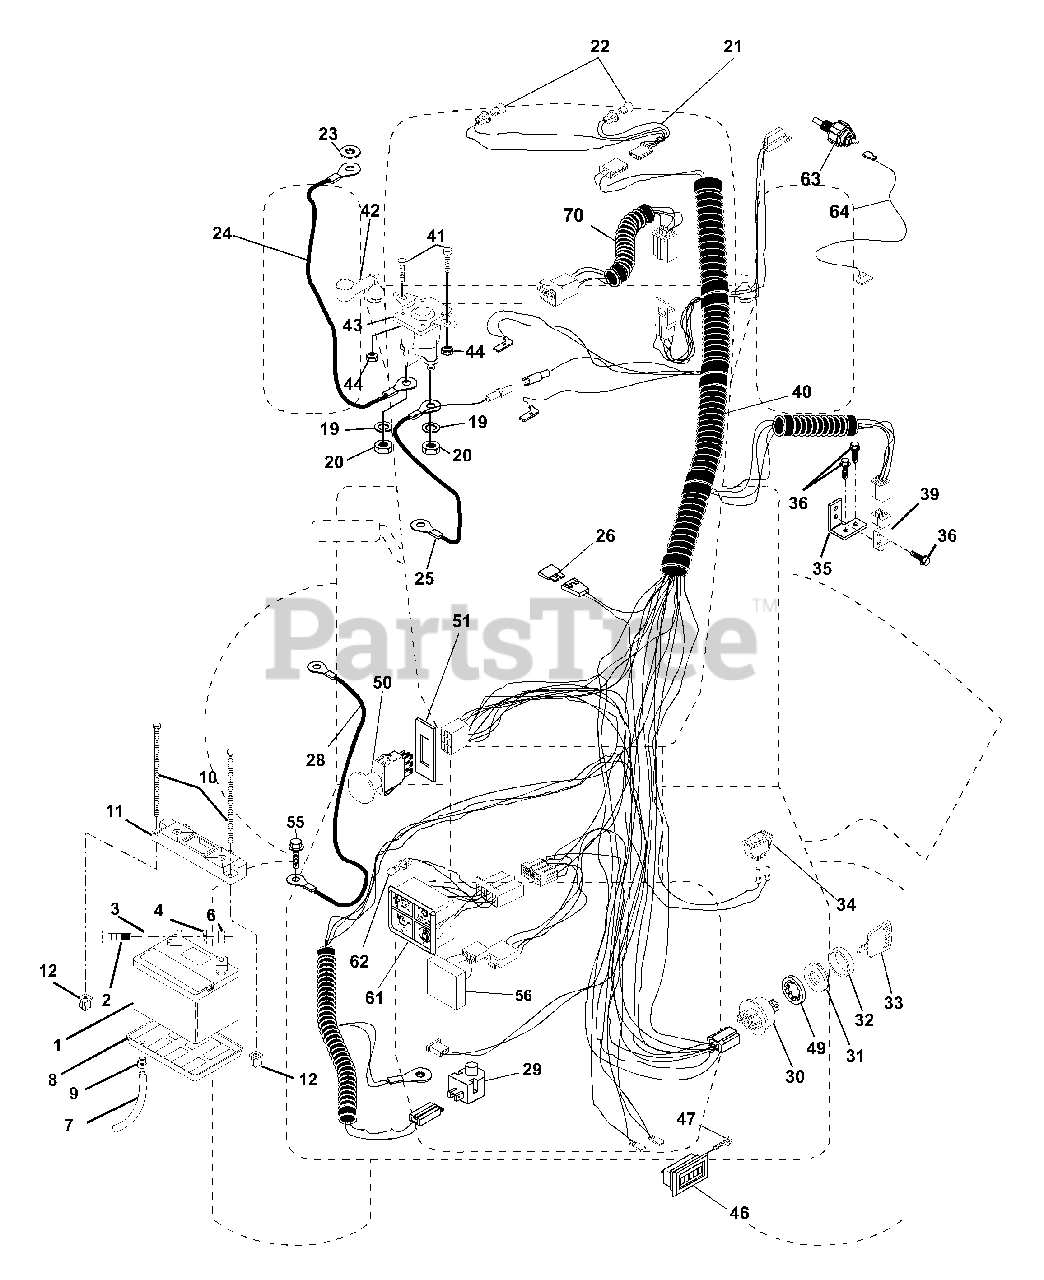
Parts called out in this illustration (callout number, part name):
1	Battery
2	Bolt, Hex Head 1/4-20 x 3/4
3	Washer 9/32 x 5/8 x 16 Gauge
4	Washer, Lock 1/4
5	Caps, Battery
6	Nut, Hex 1/4-20
7	Tube, Tray, Battery
8	Tray, Battery
9	Clamp, Hose
10	Bolt Battery Frt 1/4-20 x 3/4 Zinc
11	Holddown Battery Dash Mount
12	Push Nut Nylon 1/4" Battery Fnt.
19	Washer, Lock 1/4
20	Nut, Hex, Jam 1/4-20
21	Harness, Socket, Light
22	Bulb, Light
24	Cable Starter 6 Ga. 11" Red
25	Cable 6 Ga. Red 22' W/16 Wire
28	Cable, Ground 21" Black 6 Ga.
29	Switch, Plunger
30	Switch, Ignition
31	Nut, Ignition
32	Bezel, Ignition
33	Key, Molded
34	Switch, Light
35	Bracket Switch Interlock
36	Screw, Hex Tap #10-24 UNC
39	Switch, Intlk 4 Term
40	Harness, Ignition
41	Bolt, Hex 1/4-20 x 3/4
42	Cover, Terminal
43	Solenoid
44	Nut, Hex, Keps 1/4-20
46	Meter, Hour
47	Screw #10-24 x 1/2
49	Washer Lock Internal Tooth 5/8
50	Switch, P.T.O.
51	Ring, Retainer PTO
55	Screw Thdrol 5/16-18 x 1/2
56	Sensor, Low Voltage
61	Package, Light
62	Bulb Dashboard Light 27 amp.
63	Switch Engine Oil Pressure
64	Wire Lead Sentry Vanguard
70	Harness Eng. Koh. Tw 16 AR O Pump
